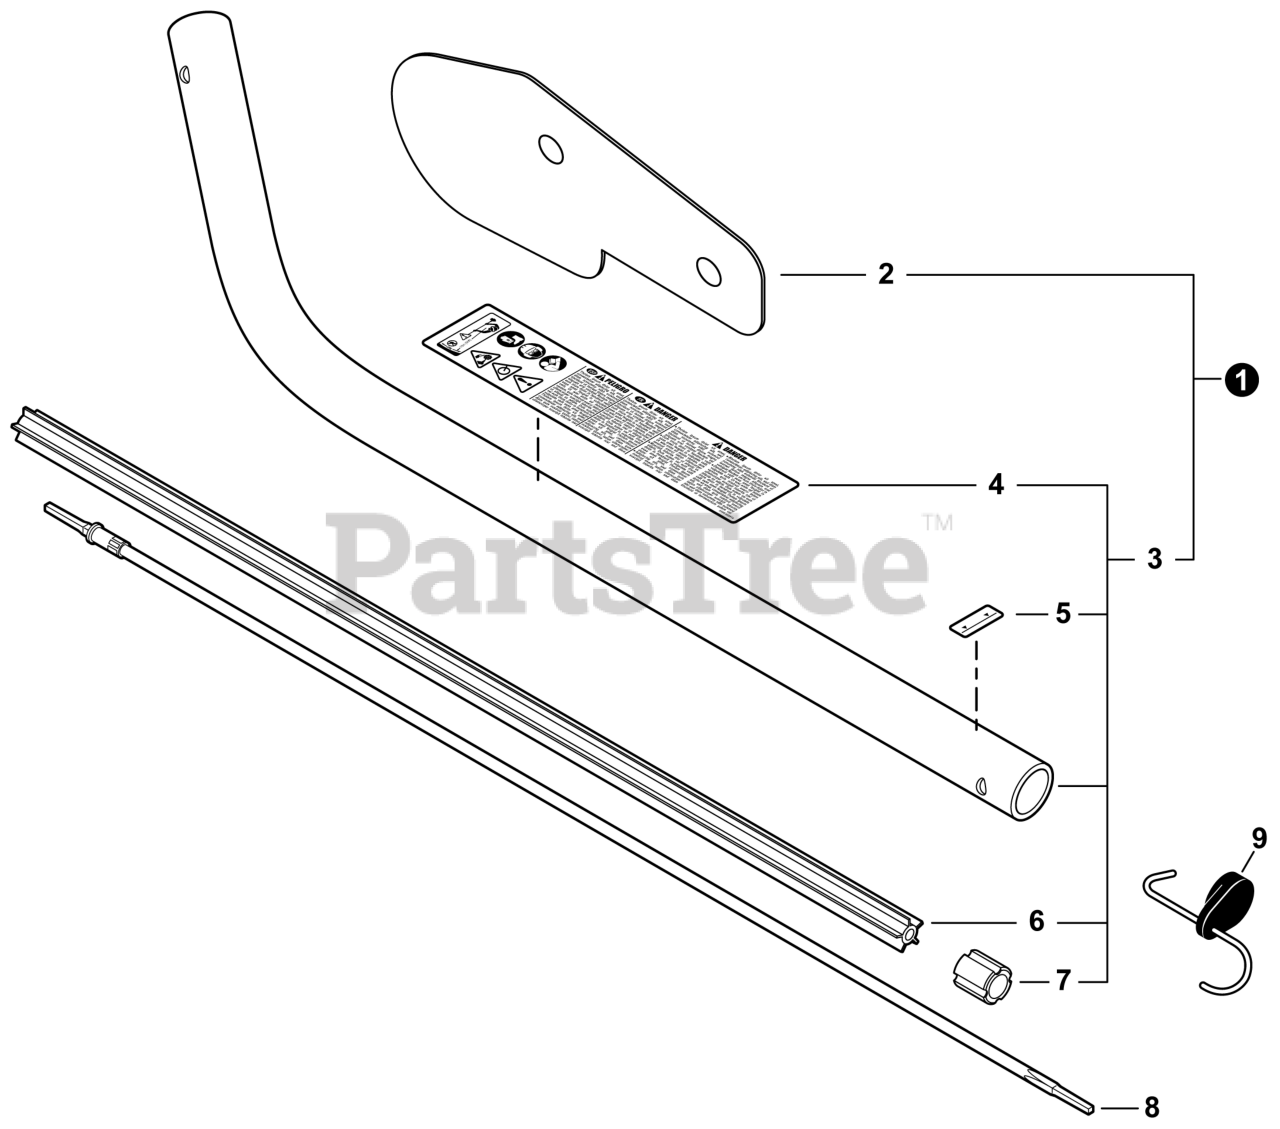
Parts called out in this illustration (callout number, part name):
1	MAIN PIPE KIT
2	PLATE, SHIELD
3	MAIN PIPE ASSY
4	LABEL - CAUTION
5	LABEL - ALIGNMENT
6	LINER - FLEXIBLE
8	DRIVESHAFT - FLEXIBLE
9	HANGER, ATTACHMENT
